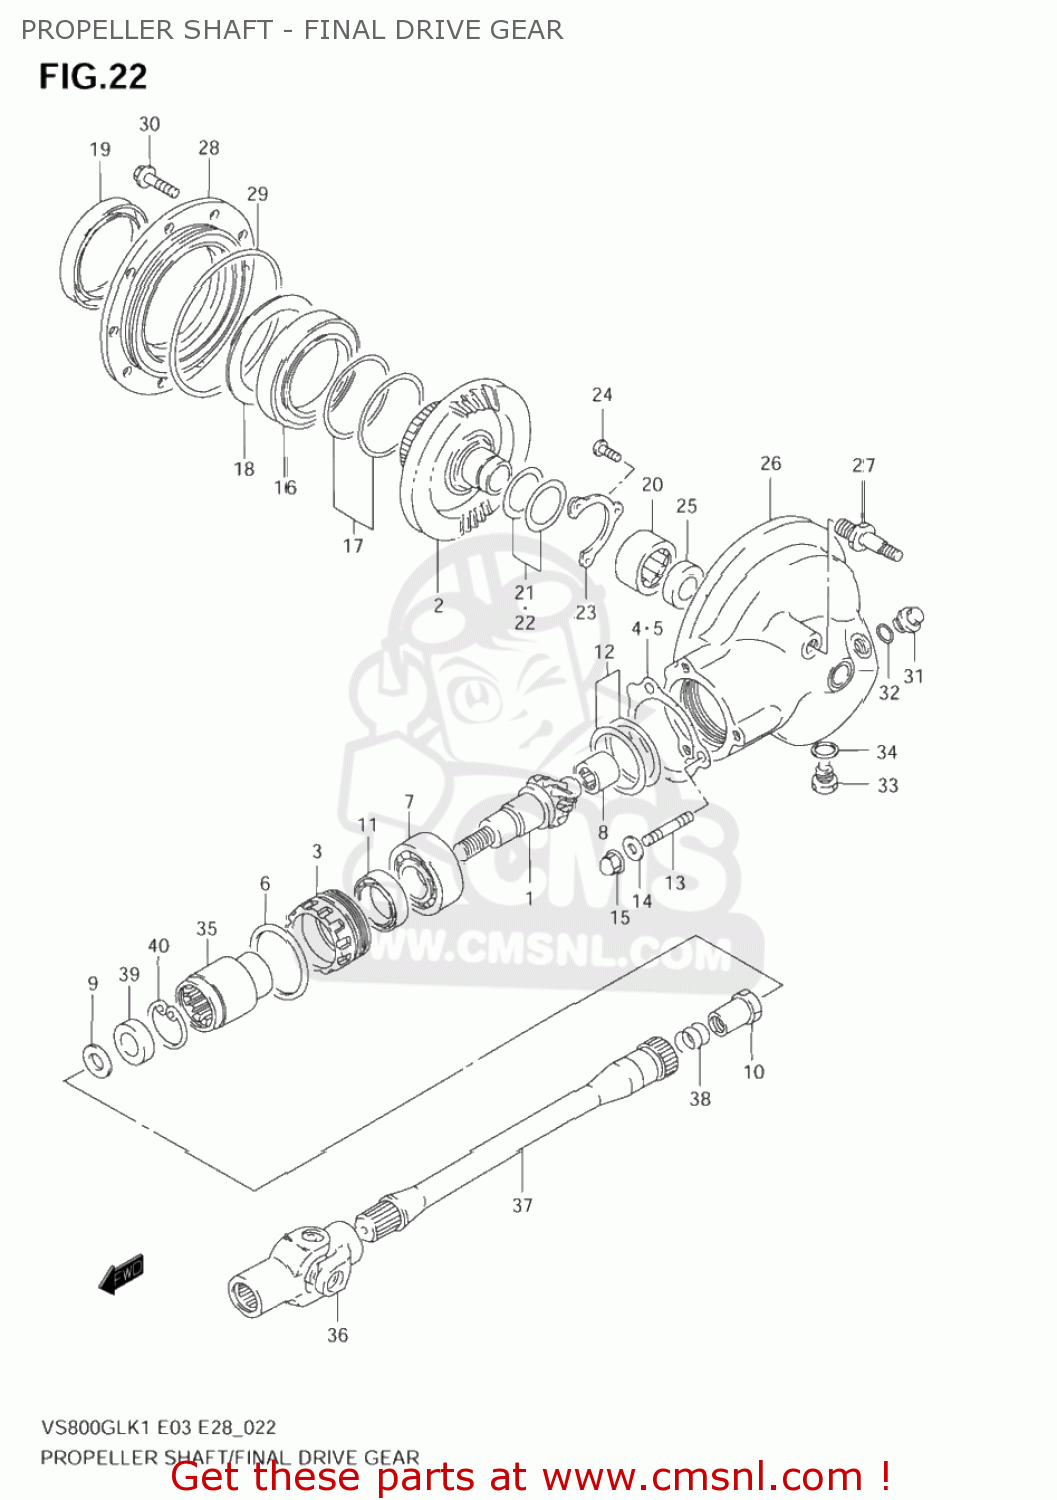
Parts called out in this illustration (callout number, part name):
1	GEAR,FINAL DRIVE BEVEL(NT:11)
2	GEAR,FINAL DRIVEN BEVEL(NT:34)
3	STOPPER,FINAL DRIVE BEARING
4	PLATE,BEARING STOPPER
5	PLATE,BEARING STOPPER
6	O RING(D:1.9,ID:61.6)
7	BEARING(30X62X23.8)
8	BEARING(17X32X16)
9	WASHER(16X29X4)
10	NUT
11	SEAL,OIL(38X54X6)
12	SHIM SET,FINAL DRIVE GEAR
13	BOLT,STUD
14	WASHER
15	NUT
16	BEARING(70X110X13)
17	SHIM SET,DRIVEN GEAR BEARING
18	PLATE,FINAL DRIVEN BRG OIL
19	SEAL,OIL(70X96X16)
20	BEARING(32X46X17.7)
21	SHIM SET,FINAL DRIVEN GEAR
22	SHIM SET,FINAL DRIVE GEAR
23	RETAINER,FINAL DRIVEN GEAR BRG
24	SCREW
25	SEAL,OIL(30X42X7)
26	CASE,FINAL
27	BOLT,STUD
28	CASE,FINAL GEAR BEARING
29	O RING(D:3.5,ID:131.6)
30	BOLT
31	PLUG
32	O RING(D:2.4,ID:17.8)
33	PLUG(MAGNETO)
34	GASKET(13.8X18.8X4.8) (NAS)
35	COUPLING,FINAL DRIVE GEAR
36	YOKE COMP,UNIVERSAL JOINT
37	SHAFT,PROPELLER
38	SPRING
39	SEAL,OIL(28.4X48X15)
40	CIRCLIP
